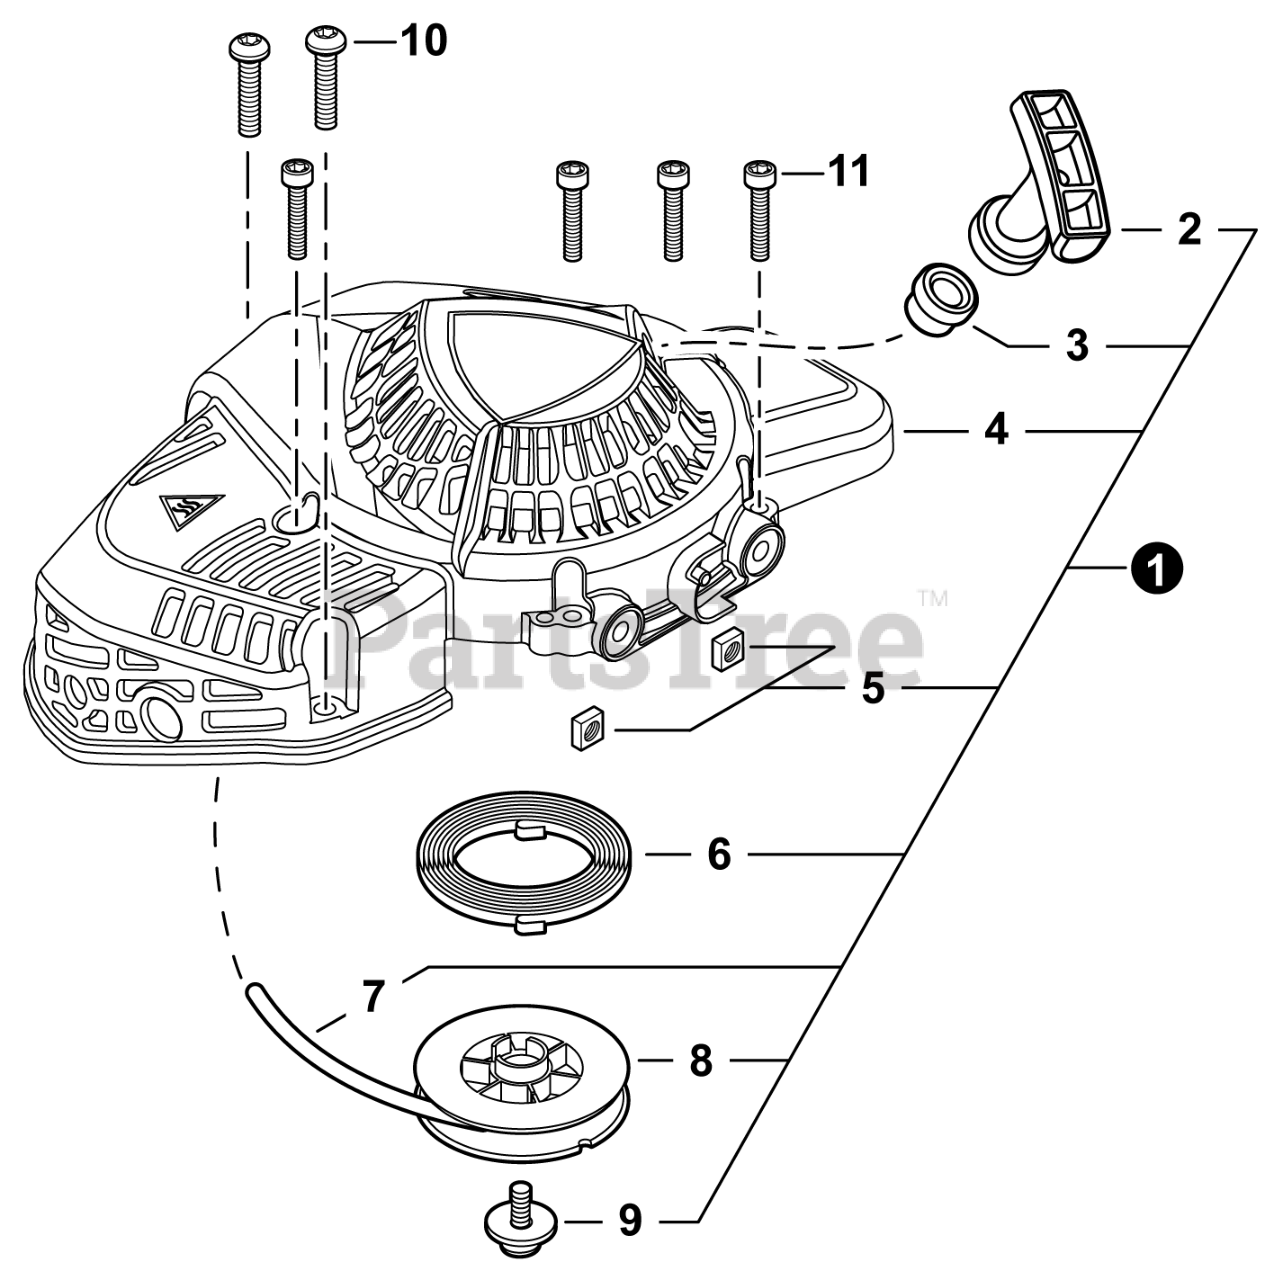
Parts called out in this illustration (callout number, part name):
1	STARTER ASSY, RECOIL
2	GRIP, STARTER
3	GUIDE, ROPE
4	CASE, STARTER
5	NUT - 5 - SQUARE
6	SPRING, RECOIL
7	ROPE, STARTER
8	REEL, ROPE
10	BOLT, TORX 5x16
11	BOLT, TORX 4x16
